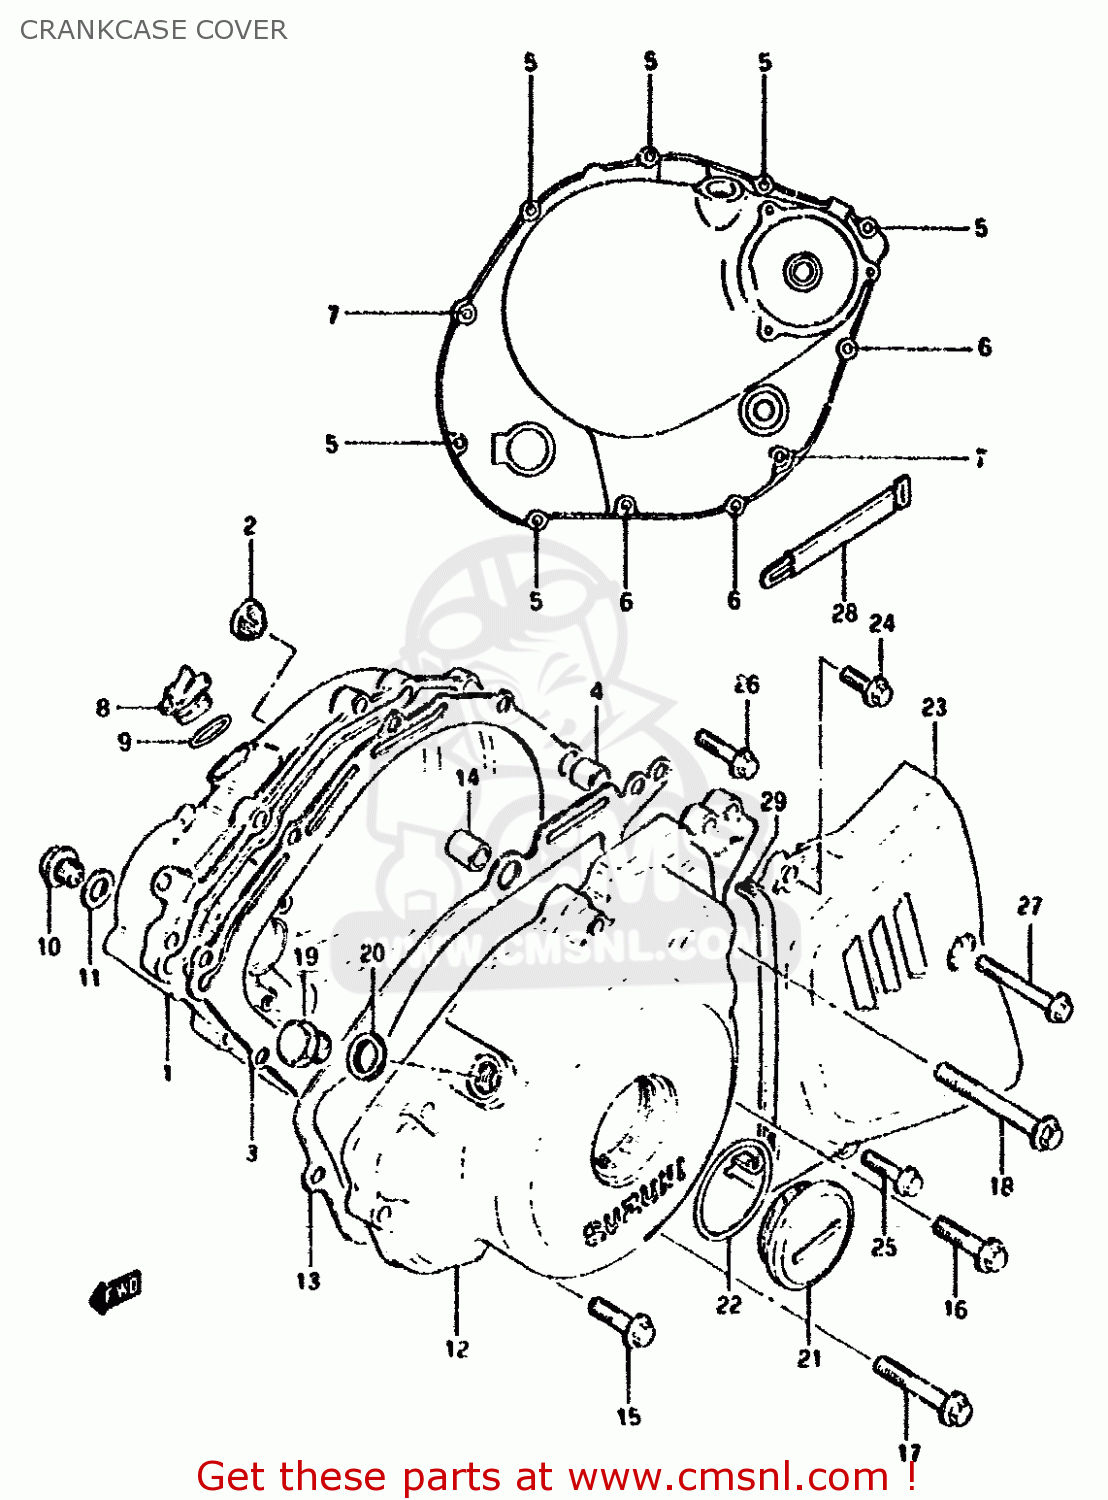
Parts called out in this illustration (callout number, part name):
1	COVER,CLUTCH
2	LENS,OIL LEVEL CHECK
3	GASKET,CLUTCH COVER (NAS)
4	PIN
5	BOLT
6	BOLT
7	BOLT
8	PLUG(20X10)
9	O RING(D:3.1,ID:16.8)
10	PLUG (14X12)
11	GASKET(14X19.2X2) (NAS)
12	COVER,MAGNETO
13	GASKET,MAGNETO COVER (NAS)
14	PIN
15	BOLT
16	BOLT
17	BOLT
18	BOLT
19	PLUG,12X9
20	GASKET(12.1X16.2X3.7) (NAS)
21	PLUG,36X10
22	O RING(D:3.1,ID:32.7)
23	COVER,ENGINE SPROCKET
24	BOLT
25	BOLT
26	BOLT
27	BOLT
28	CLAMP L:110
29	DAMPER,ENGINE SPROCKET COVER
